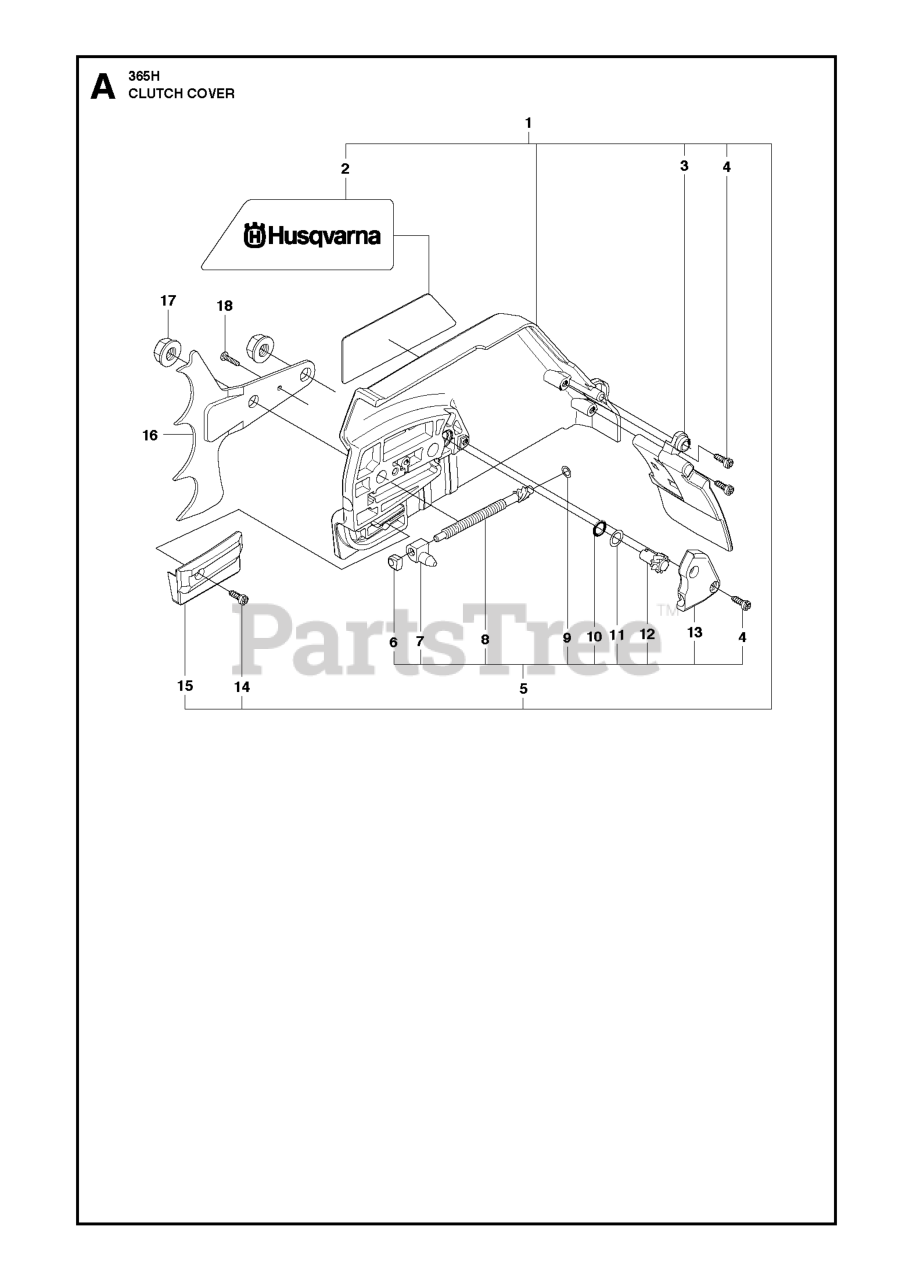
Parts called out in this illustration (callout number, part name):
1	CLUTCH COVER ASSY
4	SCREW CITXPANT
5	KIT-CHAIN TENSIONER
8	WORM SCREW / ADJUSTER
12	WORM WHEEL
14	SCREW CITXPANT
15	CHAIN GUIDE
16	SPIKE OUTER
17	NUT M8 FLANGE
18	SCREW CITXPANT
